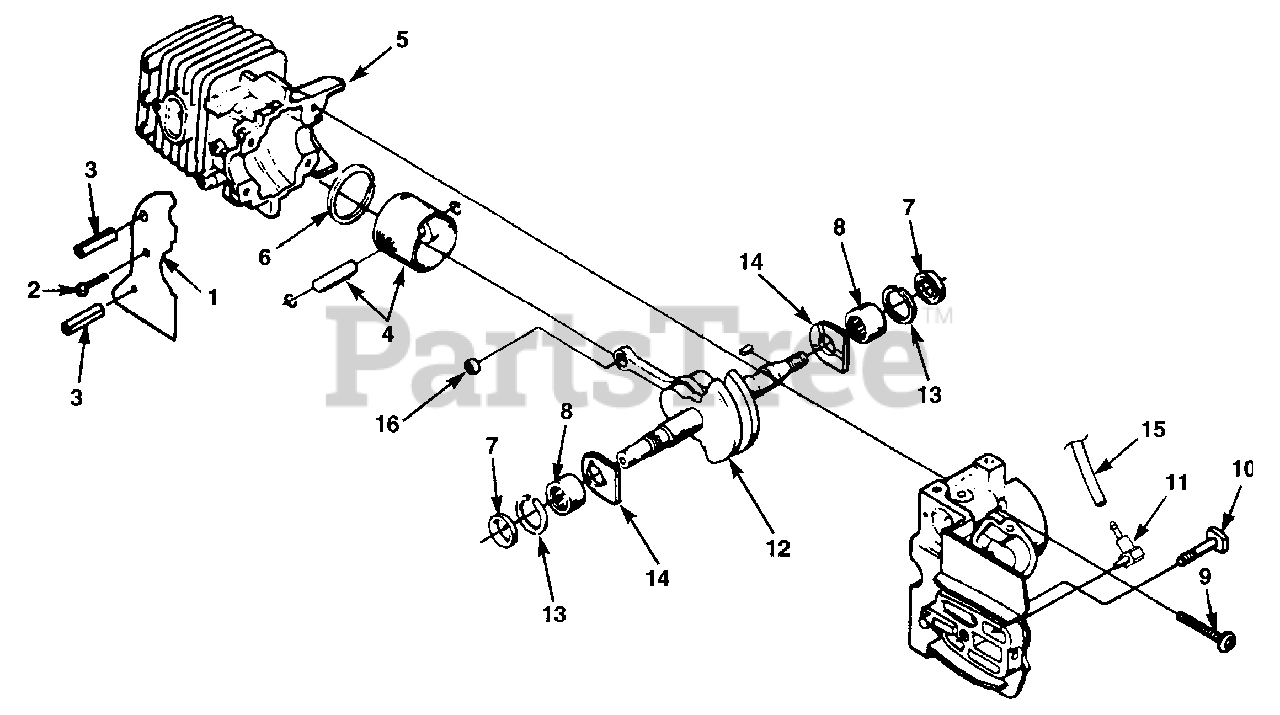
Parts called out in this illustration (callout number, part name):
1	SAW DUST SHIELD
4	PISTON & PIN ASSY.
5	CYLINDER
6	RING - Piston
7	SEAL - Shaft
8	BEARING - Needle
9	SCREW - Torx Pan Hd. (10-24 x 1 1/8")
10	BOLT - Guide Bar
11	VALVE - Check
12	CRANKSHAFT - Rod and Bearing
13	SEAL z - Shaft
14	WASHER - Thrust
15	TUBING - Rubber (Oil Line) (8")
16	BEARING - Wrist Pin
